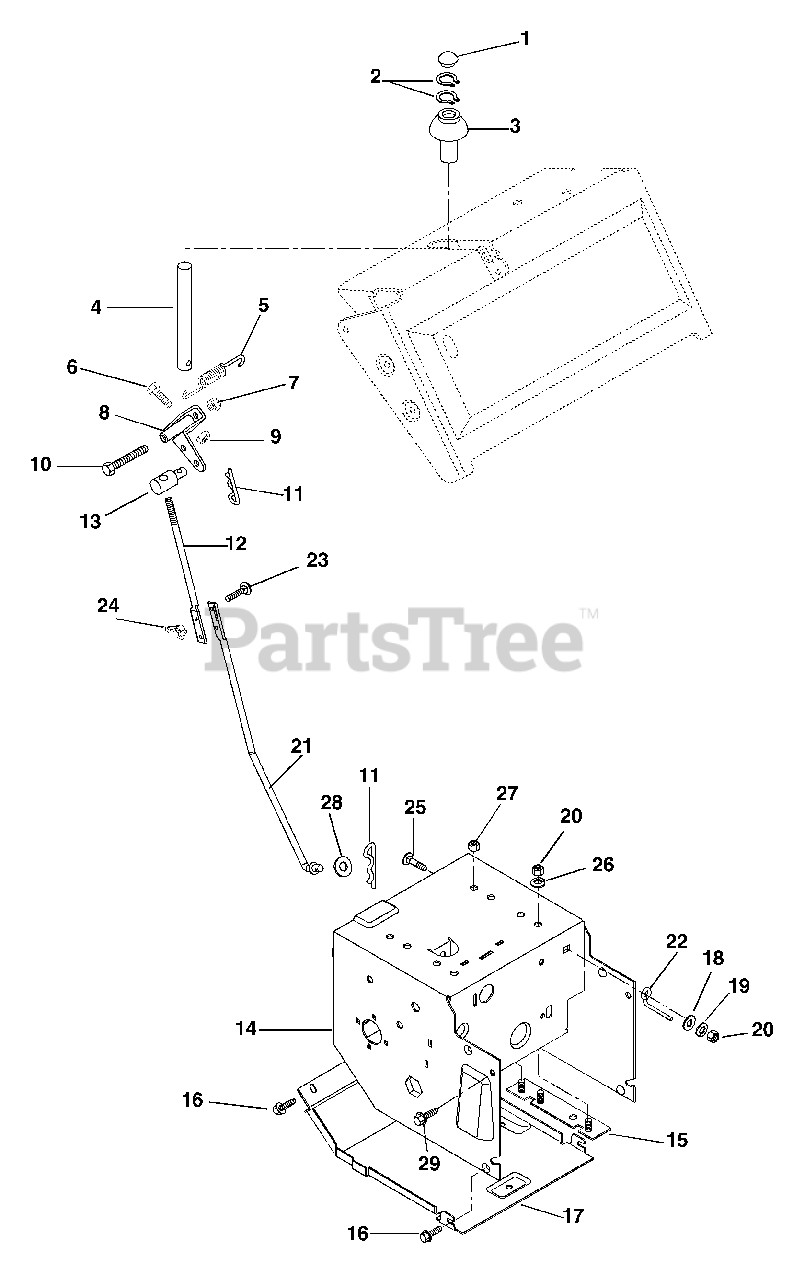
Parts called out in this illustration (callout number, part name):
1	HOLE PLUG
2	RG-RTNG-EXT .500X.015
5	SG-TENS .055X.33X1.31 WLD 7
6	@BLT-HEX .25-20X1.00 GR5 YWZC
7	@NUT-LK-CTR .31-18 YWZC
9	@NUT-LK-CTR .25-20 YWZC
10	@BLT-HEX .31-18X3.50 GR5 YWZC
11	PIN-HAIR INT .08X.18X1.18 YWZC
12	ROD, SHIFT-UPPER
13	PIVOT, ROD
15	ENGINE MOUNT, 5L,7L,8R
16	@SCR-TAP .25-20X.37 HWH YWZ TR
17	COVER BOTTOM
18	@WSHR-FL-STL.38X.875X.083 YWZC
19	@WSHR-LK .31X.078 REG YWZC
20	@NUT-HEX .31-18 YWZC
21	ROD, SHIFT-LOWER
22	BELT FINGER LOWER
23	@BLT-RDHDSQNK .25-20X1.00 G5YZ
24	NUT-LK WING .250-20 YWZC
25	@BLT-RDHDSQNK .31-18X1.00 G5YZ
26	WSHR-LK .312X.097 HVY YWZC
27	@NUT-LK-NYL .312-18 YWZC
28	@WSHR-FL-STL.531X1.06X.095YWZC
29	@SCR-TAP .38-16X.50 HWH TR YWZ
